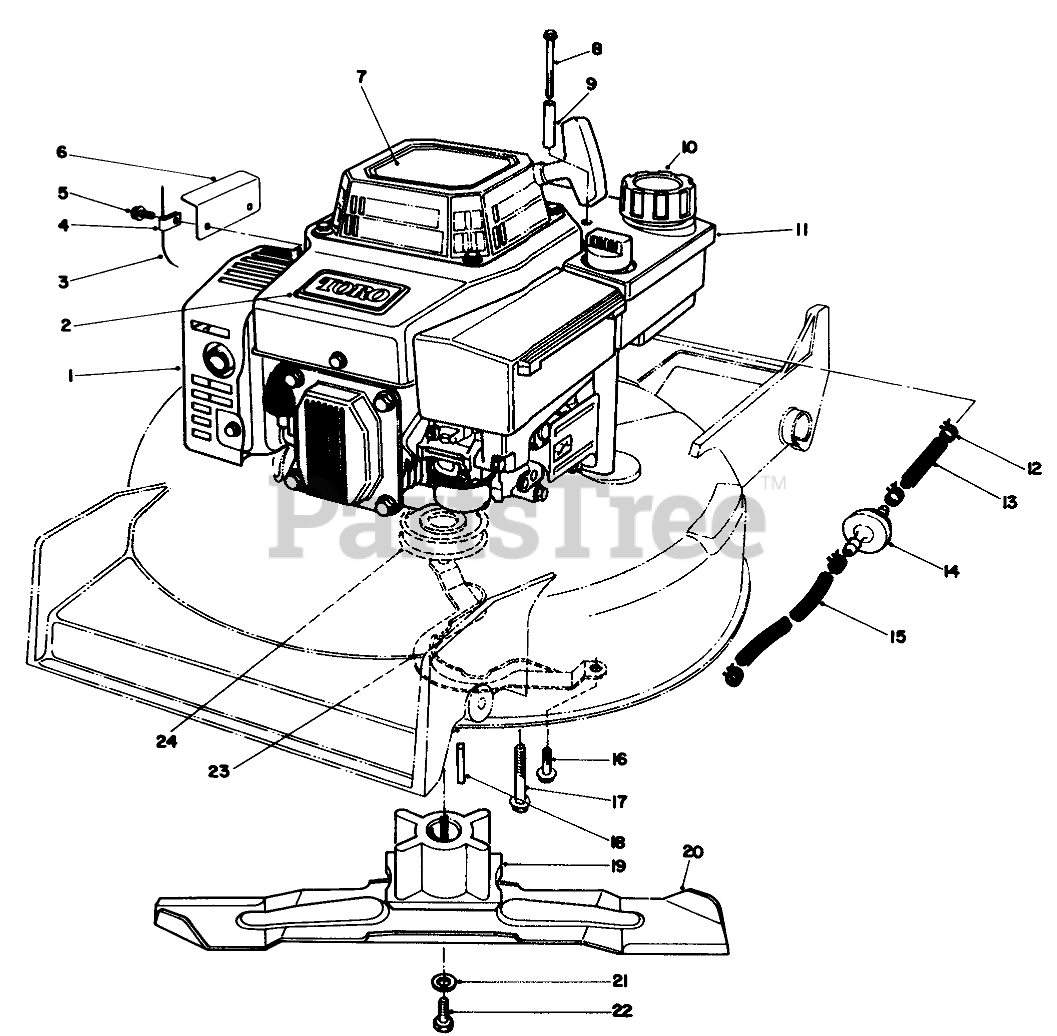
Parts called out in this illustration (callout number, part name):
2	TORO LOGO PLT
3	Wire Assembly
4	CLAMP-CABLE
5	THO FORM SCREW M6 X 1
6	FLYWHEEL SHIELD
7	DECAL-HV INT'L
8	THRD FORMING SCREW
9	TUBULAR SPACER
10	GAS CAP ASM
11	TANK ASM
12	CLAMP-FUEL LINE
13	LINE-GAS
14	FILTER-FUEL
15	HOSE-FUEL
16	Screw
17	SCREW-HWHTF
18	KEY-SQUARE
19	Retainer Blade
20	BLADE-21in
21	WASHER-LOCK
22	SCREW-BLADE
23	BELT GUIDE
24	PULLEY-DRIVER
